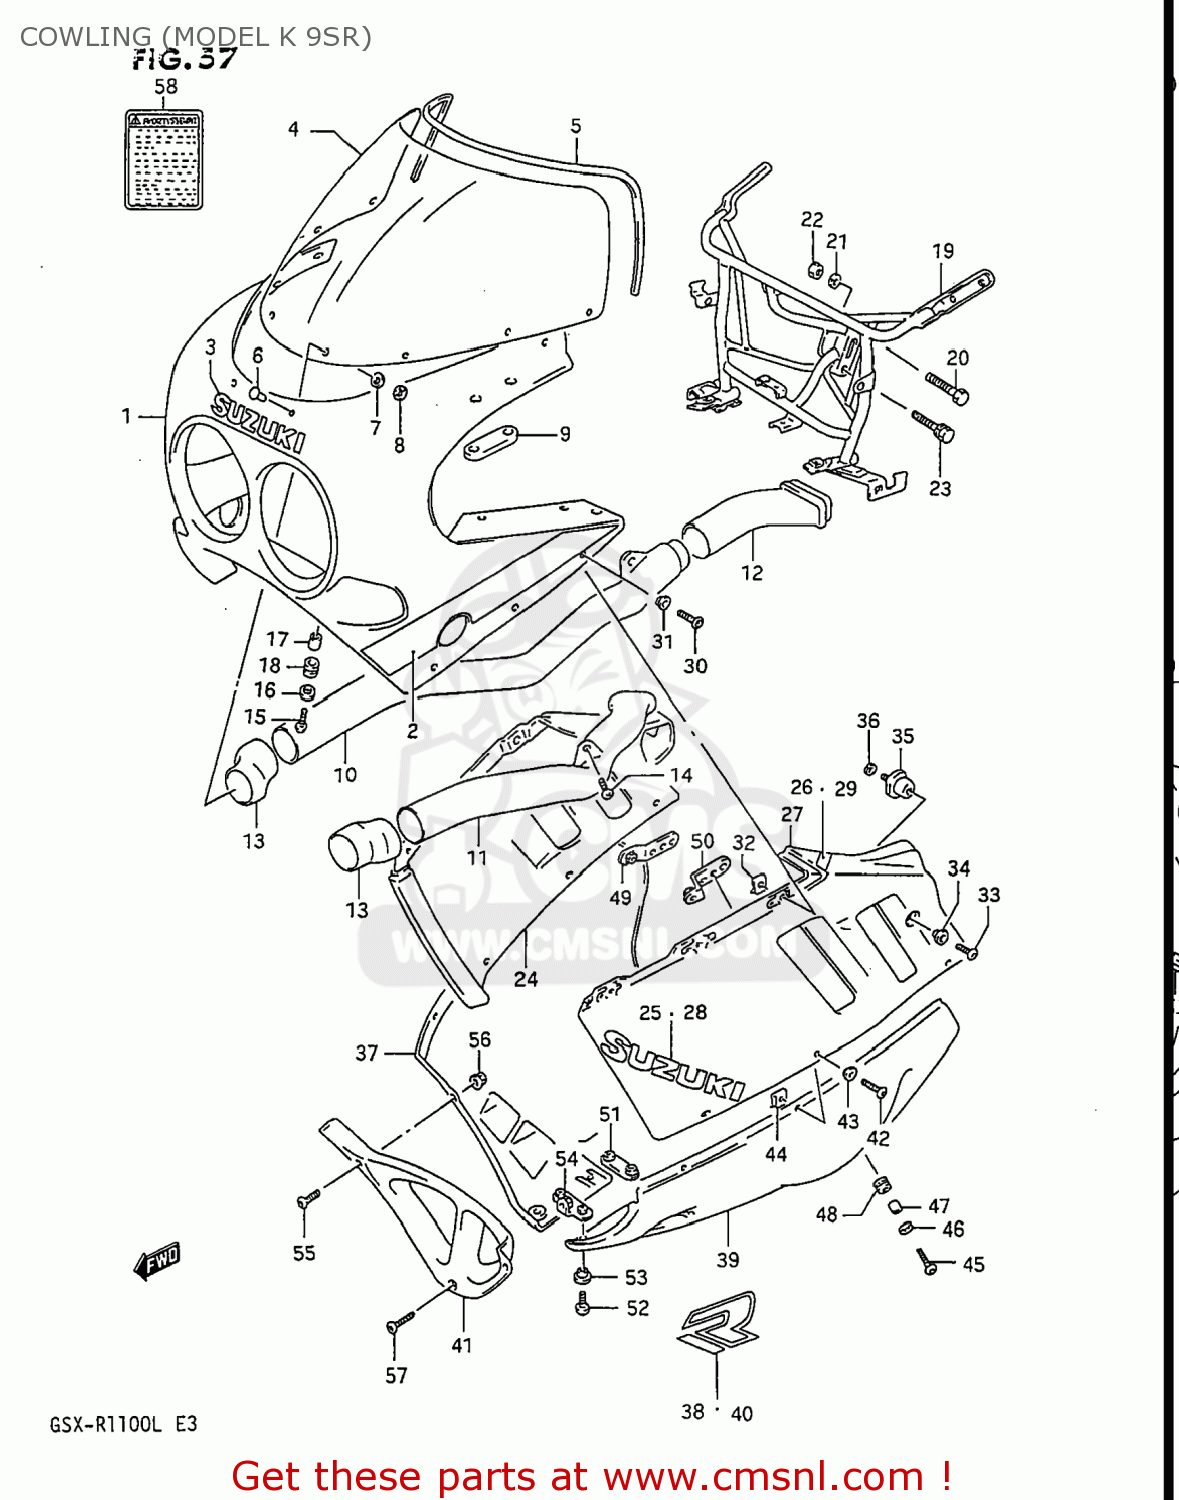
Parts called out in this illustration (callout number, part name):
1	BODY ASSY,COWLING
2	TAPE SET,COWLING,UPPER
3	EMBLEM,COWLING,FRONT
4	SCREEN SET,WINDOW
5	MOLDING
6	PIN,WINDSCREEN
7	CUSHION
8	NUT
9	CUSHION,RR VIEW MIRRORR
10	PIPE,AIR INTAKE FR,R
11	PIPE,AIR INTAKE,FRONT
12	PIPE,AIR INTAKE RR,R
13	JOINT,AIR INTAKE
14	SCREW, CENTER
15	SCREW(6X20)
16	WASHER(6.5X18X1)
17	SPACER
18	CUSHION
19	BRACE,COWLING
20	BOLT
21	WASHER,LOCK,8.
22	NUT ,8MM
23	BOLT
24	COVER ASSEMBLY,COWLING
25	EMBLEM
26	TAPE,COWLING SIDE,RIGHT
27	COVER COMP,COWLING SIDE,LEFT
28	EMBLEM
29	TAPE,COWLING SIDE,LEFT
30	SCREW(5X18)
31	WASHER(5.2X14X1.5)
32	NUT,HEADLAMP HOUSING,UPPER
33	SCREW(6X12)
34	WASHER(6.3X16X1.5)
35	CUSHION,COWLING
36	WASHER,LOCK
37	COWLING,UNDER,R
38	EMBLEM,COWLING UNDER
39	COWLING COMP,UNDER,LEFT
40	EMBLEM,COWLING UNDER
41	COWLING,UNDER,CENTER
42	SCREW(5X18)
43	WASHER(5.2X14X1.5)
44	NUT,HEADLAMP HOUSING,UPPER
45	SCREW(6X20)
46	WASHER(6.5X18X1)
47	SPACER
48	CUSHION
49	BRACKET
50	BRACE,COWLING UNDER,LH
51	BRACE,COWLING LWR COVER RR
52	SCREW(6X16)
53	WASHER(6.3X16X1.5)
54	BRACE,COWLING LWR COVER
55	SCREW(5X14)
56	NUT
57	SCREW(6X16)
58	LABEL (WARNING)
